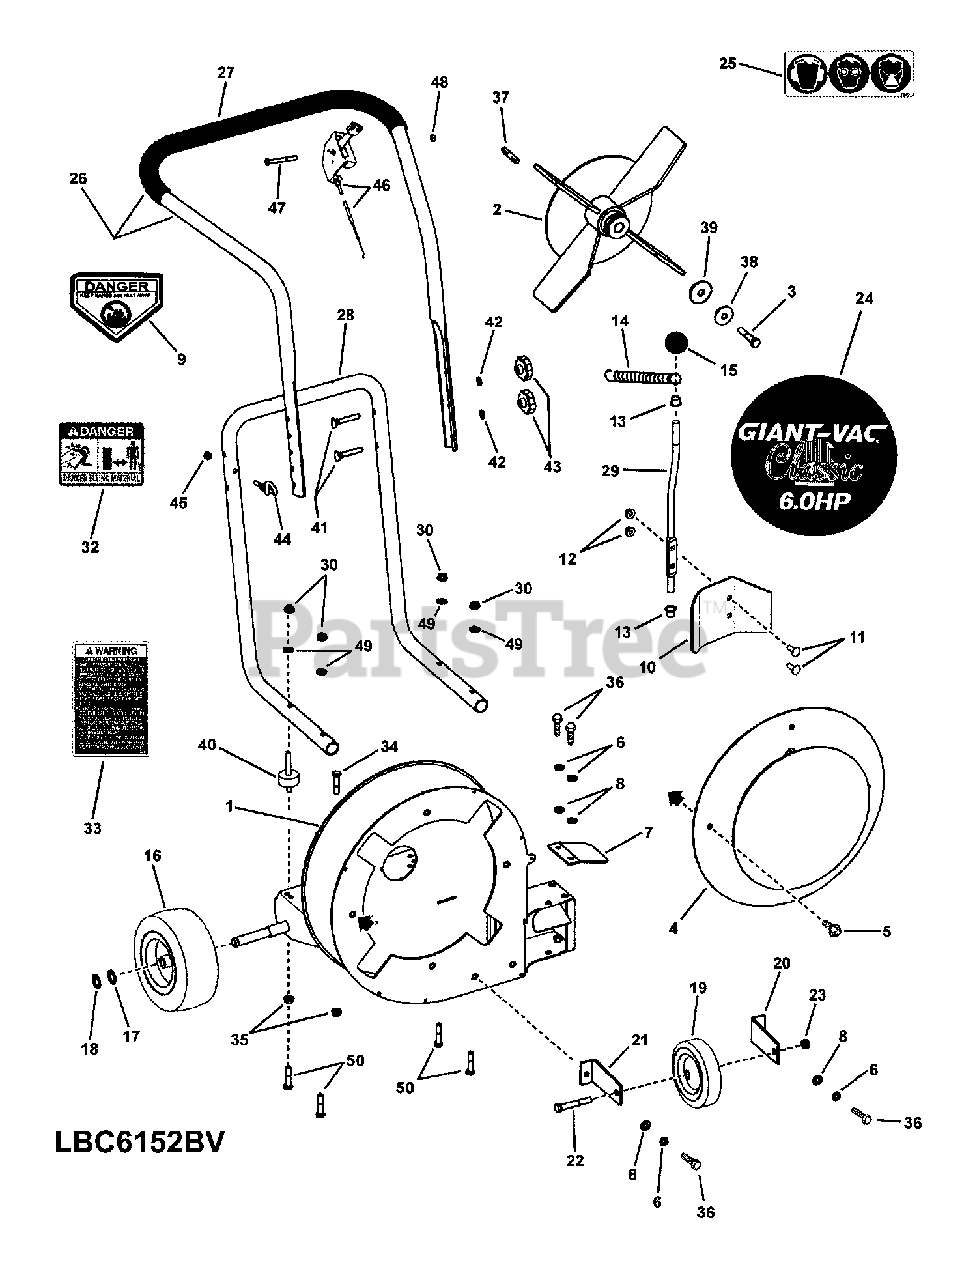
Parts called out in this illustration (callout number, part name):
1	WELDMENT, Base & Housing, 52 Classic
2	WELDMENT, Steel Impeller, 4 Blade, 15.00 O.D.
3	SCREW, 3/8-24 x 2" Hex Head Cap, GR 5
4	WELDMENT, Intake Baffle
5	BOLT, 5/16-18 x 1/2" Hex Flange Lock
6	WASHER, 5/16" Split
7	DEFLECTOR, Side Air
8	WASHER, .34 x .69 x .08 Flat
9	DECAL, Danger, Cut Finger (CPSC)
10	DOOR, Forward Air Control
11	BOLT, 1/4-20 x 3/4" Short Square Neck, GR 5
12	NUT, 1/4-20 Hex Flange Lock, GR 5
13	BEARING, 3/8 Clip
14	SPRING, Extension
15	KNOB, #230 Dimco (3/8-16 thread)
16	ASSY, Wheel & Tire, Sawtooth 4.10/3.50-4 Kenda
17	WASHER, .64 x .99 x .05 Flat
18	RING, External Retaining
19	WHEEL, 6.00 x 1.50 Semi-Pneumatic
20	BRACKET, Caster- RH
21	BRACKET, Caster- LH
22	SCREW, 3/8-16 x 2-1/2" Hex Head Cap, GR 5
23	NUT, 3/8-16 Hex Center Lock, GR 5 or B
24	DECAL, 6.0 HP Classic Leaf Blower, Giant-Vac
25	DECAL, Personal Protection
26	ASSEMBLY, Upper Handle & Grip- Narrow
27	GRIP, 1.0 x 21-1/2" Foam
28	HANDLE, Lower Folding, Narrow, Blower
29	ROD, Door Front/Side Discharge
30	NUT, 5/16-18 Hex Nyloc
32	DECAL, Danger, Flying Material
33	DECAL, Leaf Blower Warning
34	SCREW, 5/16-18 x 1-1/2" Hex Head Cap, GR 5
35	NUT, 5/16-18 Hex Flange Lock, GR 5
36	SCREW, 5/16-18 x 3/4" Hex Head Cap, GR 5
37	KEY, 1/4" Square x 2"
38	WASHER, .411/.406 I.D. Cone
39	WASHER, .468 x 1.625 x .25 Flat
40	MOUNT, Vibration (5/16-18 threads, both ends)
41	BOLT, 5/16-18 x 2" Curved Head Square Neck, GR 2
42	WASHER, 5/16" Internal Tooth Lock
43	KNOB, Folding Handle
44	ROPE GUIDE (1/4-20 thread)
45	NUT, 1/4-20 Hex Center Lock, GR 5 or B
46	THROTTLE CONTROL, B&S, 35.00/1.62
47	SCREW, 1/4-20 x 2" Hex Head Cap, GR 5
48	NUT, 1/4-20 Hex Nyloc
49	WASHER, 5/16" Curved
50	SCREW, 5/16-18 x 1-3/4" Hex Head Cap, GR 5
